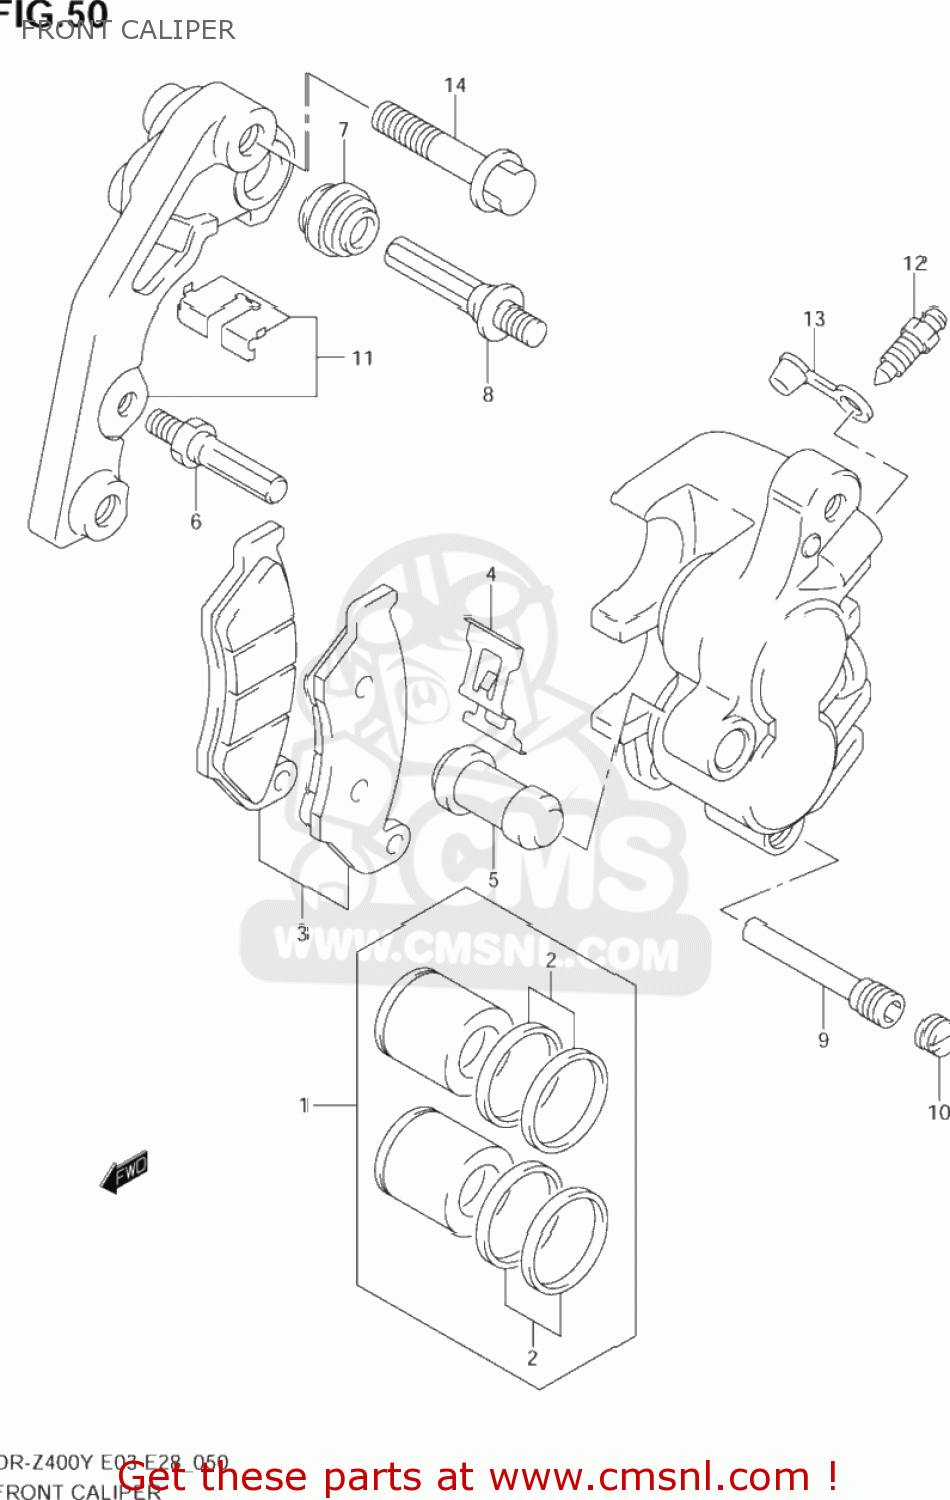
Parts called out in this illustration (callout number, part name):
1	PISTON SET
2	SEAL SET,PISTON
3	PAD SET (NAS)
4	SPRING,PAD
5	BOOT
6	BOLT
7	BOOT
8	PIN
9	PIN,HANGER
10	PLUG,PIN
11	BRACKET
12	BLEEDER
13	CAP,BLEEDER
14	BOLT(8X40)
